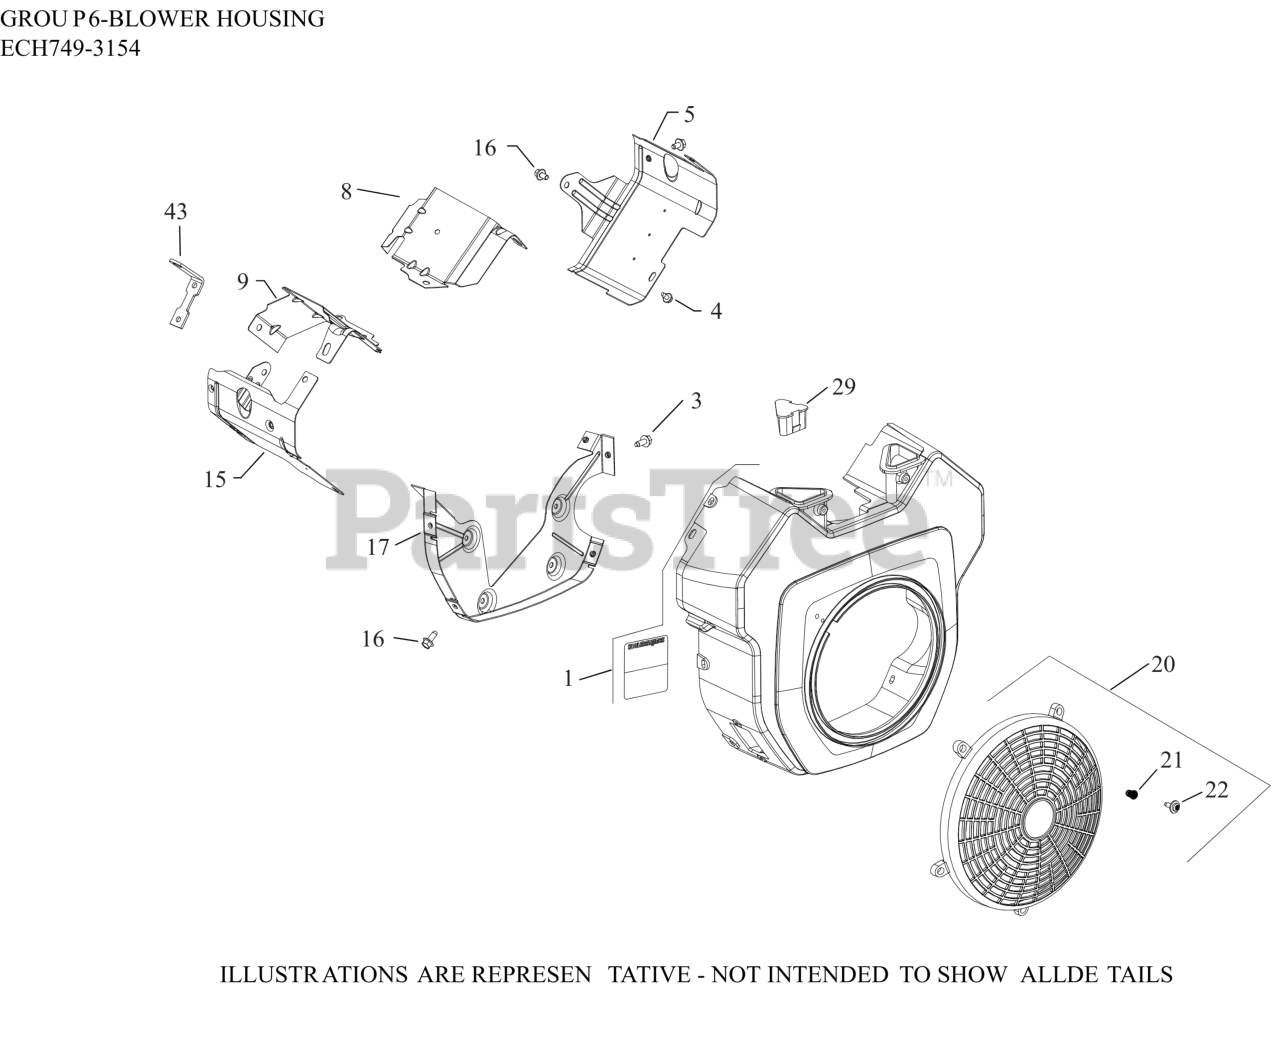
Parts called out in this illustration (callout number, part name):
1	KIT, BLOWER HOUSING
1	HOUSING, BLOWER
3	SCREW, THREAD FORMING
4	SCREW, THREAD FORMING
5	KIT, RIGHT BARREL
8	BAFFLE, VALLEY #1 CYLINDER
9	BAFFLE, VALLEY #2 CYLINDER
15	BAFFLE LEFT BARREL
16	SCREW, THREAD FORMING
17	PLATE, BACKING
17	KIT, BACKING PLATE
20	KIT, FIXED GUARD
21	INSERT, THREADED (M5)
22	SCREW, SEMS
29	COVER, BLOWER HOUSING
43	STRAP, LIFTING
